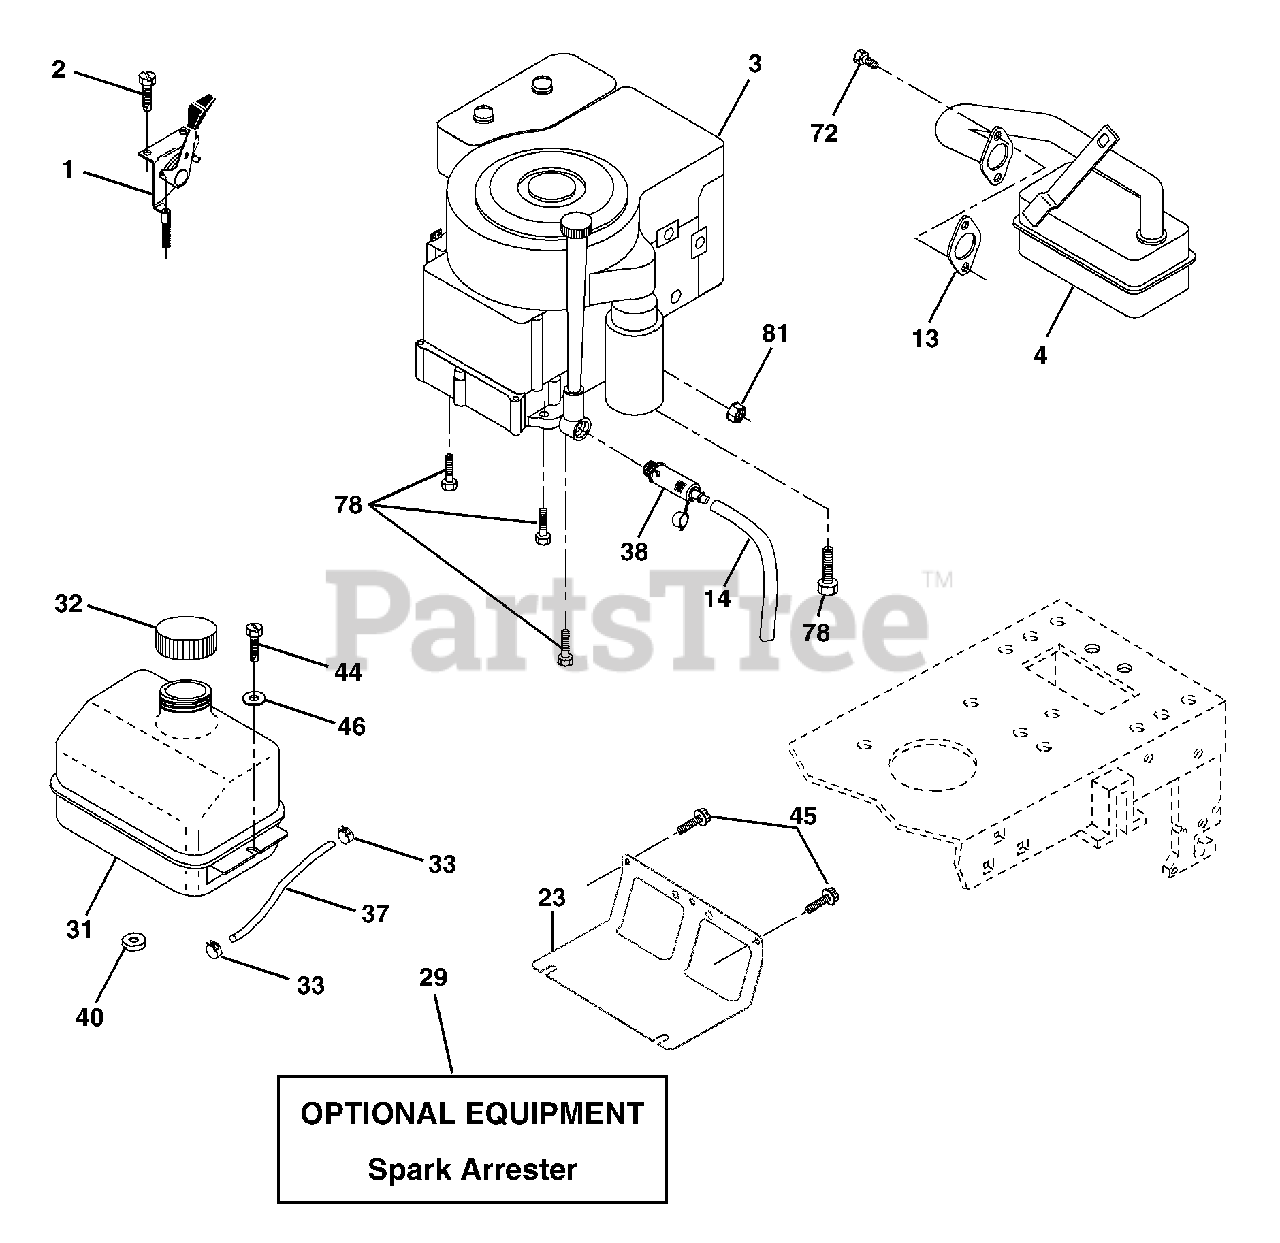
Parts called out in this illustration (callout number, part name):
1	Control Th/ch Flag
2	Screw Hex Thd Cut 1/4-20 x 1/2
13	Gasket Eng
14	Tube Drain Oil Easy
23	Shield Brn/Dbr Guard
29	Kit Spark Arrestor (Flat Scrn)
31	Tank Fuel Front
32	Cap Asm Fuel W/sym Vented
33	Clamp Hose Black
37	Line Fuel 20"
38	Plug Drain Oil Easy
40	Bushing Snap Nyl Blk Fuel Line
44	Screw Hexwsh Thdrol 1/4-20 x 3/4
45	Screw Hexwsh Thdr 3/8-16 x 3/4
46	Washer 9/32 x 7/8 x 16 Ga.
72	Screw Socket Head 5/16-18 x 1
78	Screw 3/8-16 x 1-1/4
81	Nut Keps Hex 1/4-20 unc
